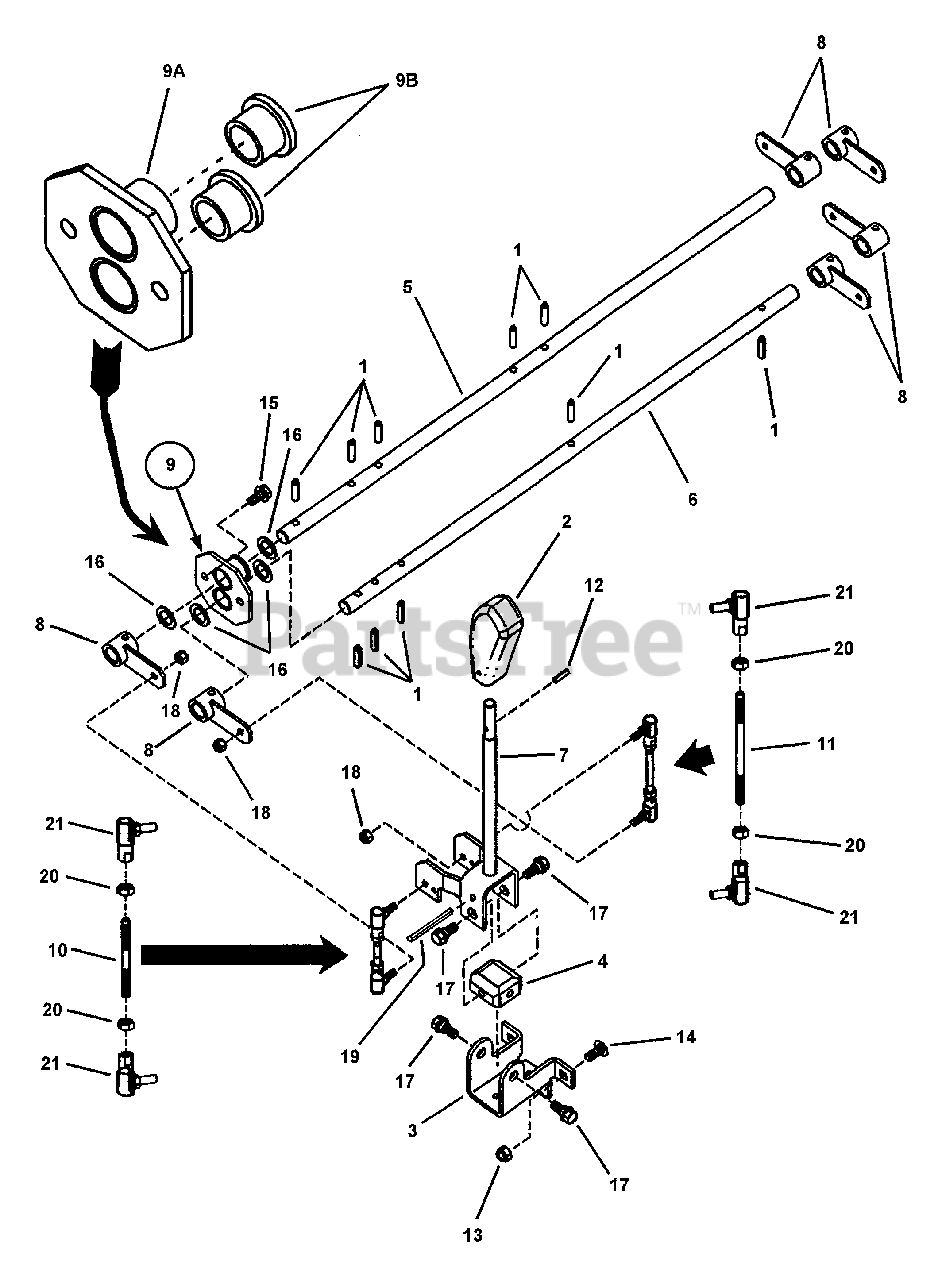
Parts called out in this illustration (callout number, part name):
1	ROLL PIN, 1/4 x 1"
2	HANDLE, Plastic
3	BRACKET, Joystick Mounting
4	BLOCK, Pivot J-Stick Control
5	SHAFT, Upper Cross
6	SHAFT, Lower Cross
7	WELDMENT, Joystick Control Handle
8	WELDMENT, Arm/Hub
9	ASSEMBLY, Cross Shaft Support
9A	WELDMENT, Cross Shaft Support
9B	BUSHING, Teflon Impregnated
10	ROD, Threaded 1/4-28 x 2.71 long
11	ROD, Threaded 1/4-28 x 3.85 long
12	ROLL PIN 3/16 x 3/4"
13	NUT, 5/16-18 HEX NYLON LOCK
14	BOLT, 5/16-18 x 3/4" Carriage, Grade 5
15	SCREW, 5/16-18 x 5/8" Hex Washer Self-Tap
16	WASHER, 41/64 I.D. x 1" O.D. Flat
17	BOLT, 5/16-18 Shoulder
18	NUT, 1/4-28 Hex Nyloc
19	ROLL PIN, 1/4 x 2-3/4"
20	HN, 1/4F GR5 YZ
21	BALL-JOINT
